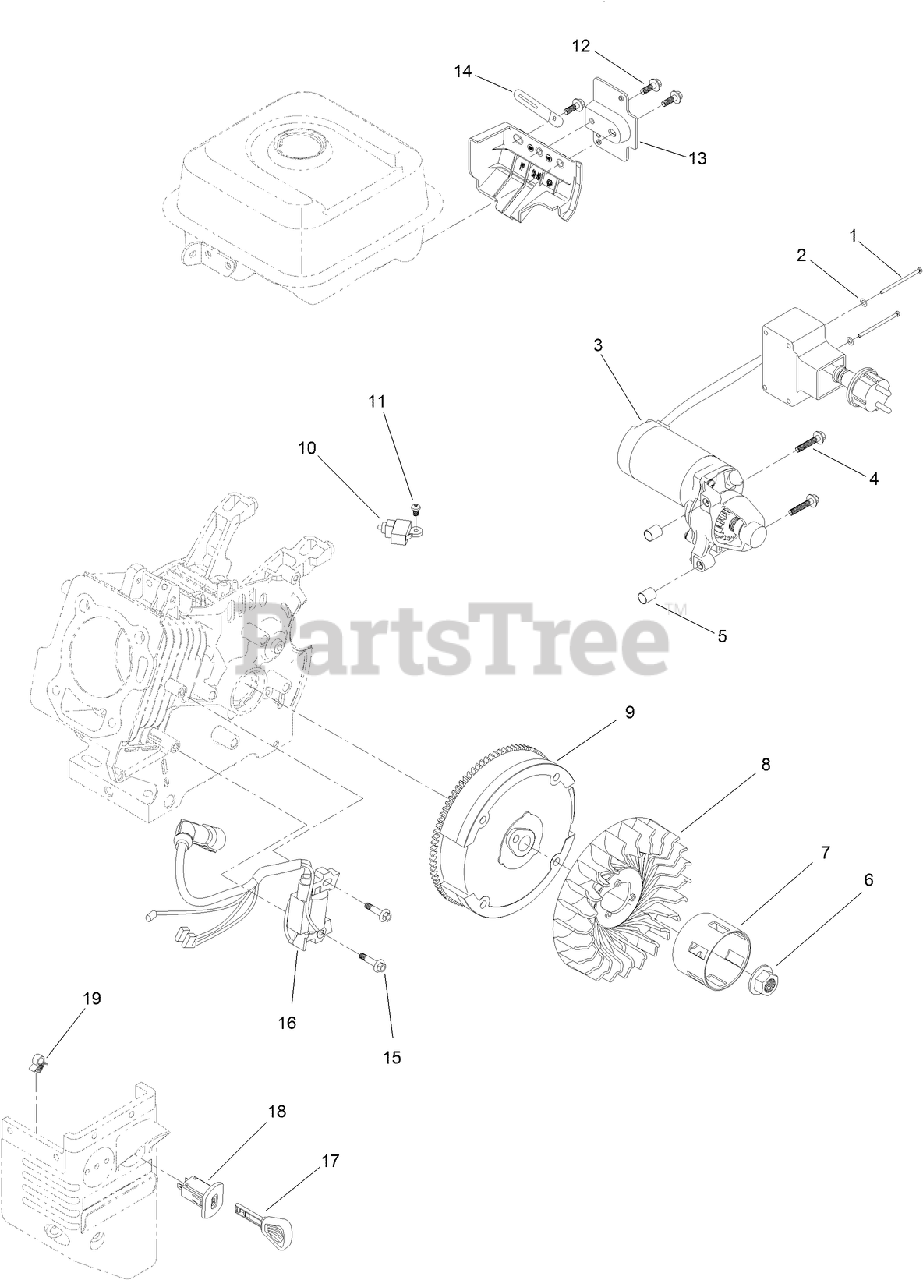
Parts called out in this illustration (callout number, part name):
1	SCREW-BHP
2	WASHER-PLAIN
3	MOTOR-STARTER
4	SCREW-FLANGE
5	PIN-DOWEL
6	NUT-FLANGE
7	CUP-STARTER
8	FAN-COOLING
9	FLYWHEEL AND RING GEAR ASM
10	SWITCH-KILL, ENGINE
11	SCREW-PPH
12	SCREW-HHF
13	BRACKET-SWITCHBOX, STARTER
14	CLIP-HARNESS, WIRE
15	SCREW-HHF
16	IGNITION COIL ASM
18	SWITCH-KEY
